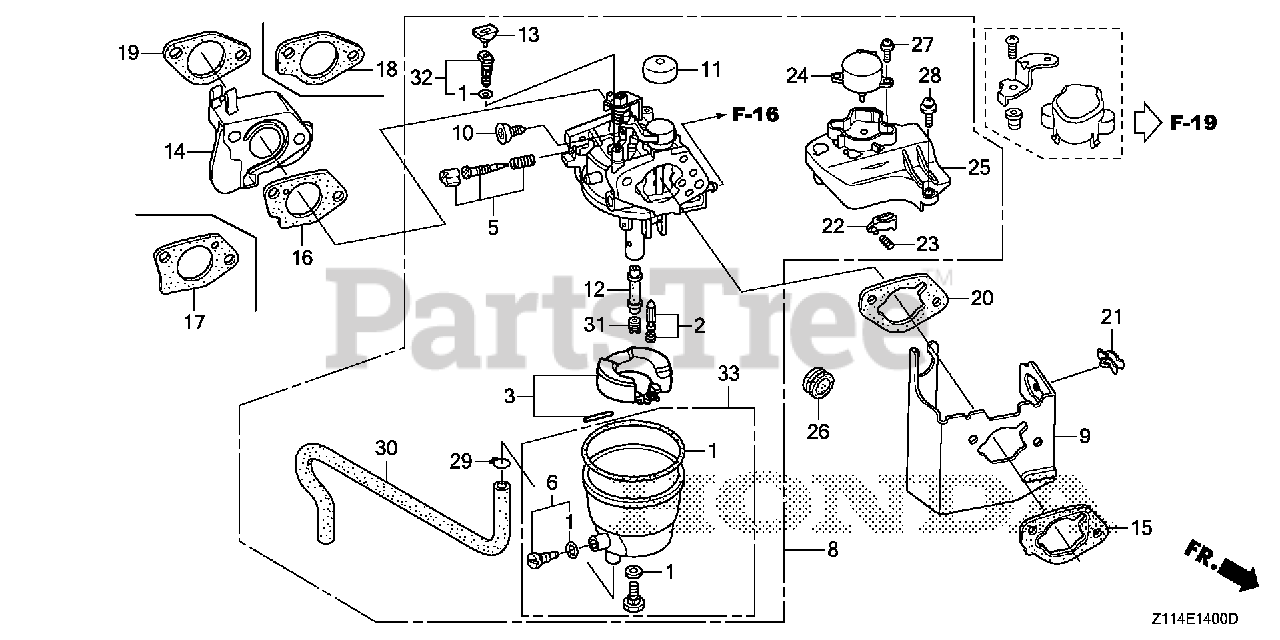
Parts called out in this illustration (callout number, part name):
1	GASKET SET
2	VALVE SET, FLOAT
4	CHAMBER SET, FLOAT
5	SCREW SET, PILOT
6	SCREW SET, DRAIN
7	SCREW SET
8	CARBURETOR ASSY. (BE82L D)
9	HOLDER, TUBE
10	SCREW, STOP
11	CAP, CHOKE DUST
12	NOZZLE, MAIN
13	COLLAR, SETTING
14	INSULATOR, CARBURETOR
15	SPACER, CARBURETOR
16	GASKET, CARBURETOR
19	GASKET, INSULATOR
20	GASKET, AIR CLEANER
21	CLIP, HARNESS
22	LEVER, LINK
23	SPRING, COMPRESSION COIL
24	MOTOR, THROTTLE CONTROL
25	BRACKET, THROTTLE MOTOR (CARBURETOR NO.)
26	GROMMET, FENDER
27	SCREW-WASHER (3X8)
28	SCREW-WASHER (4X12)
29	CLIP, TUBE (C8)
30	BULK HOSE, VINYL (4.5X8X1000) (95003-(95003-09001-60M)
31	JET, MAIN (#88)
31	JET, MAIN (#90)
31	JET, MAIN (#92)
32	JET SET, PILOT (#45)
33	BOLT KIT, FUEL CHAMBER
